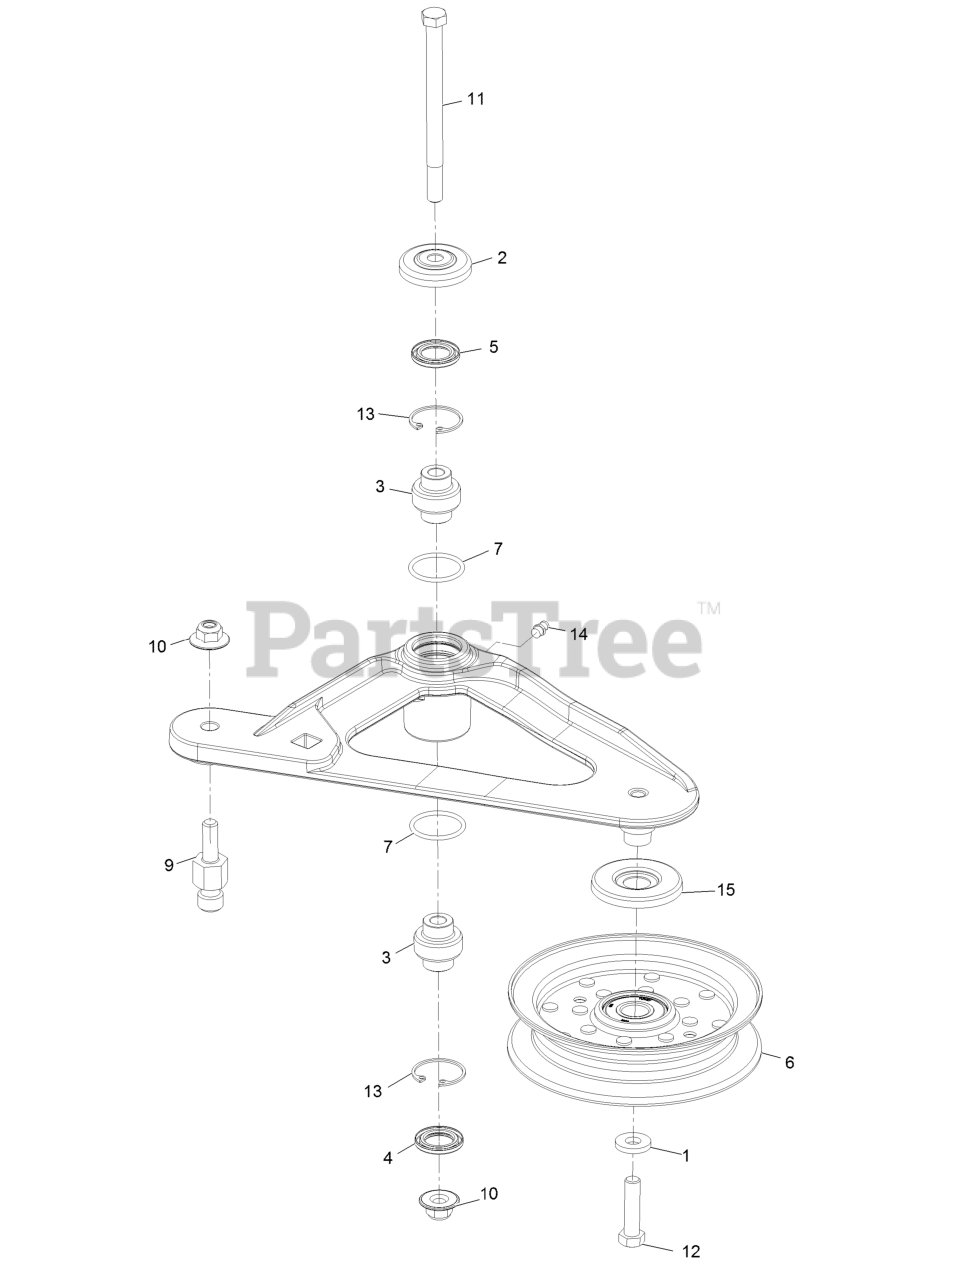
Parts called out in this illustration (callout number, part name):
2	Guard-Top
3	Bearing-Spherical
4	Seal-Lip, Double
5	Seal-Lip, Single
6	Idler-Pulley, Flat
9	Pin-Spring, Anchor
10	Nut-Flange, NI
11	Screw-Shoulder, HH
12	Screw-HH
13	Ring-Snap
14	Fitting-Grease
15	Shield-Guard, Dust
